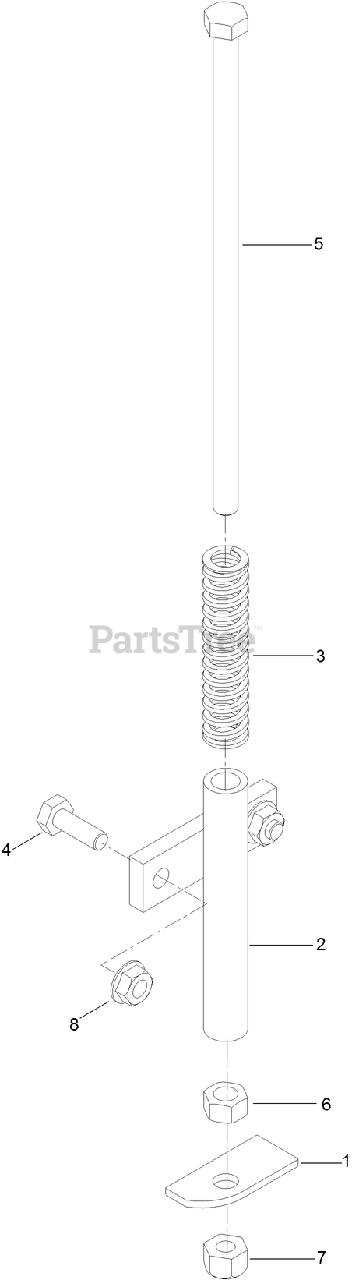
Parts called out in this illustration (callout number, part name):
1	PLATE-SWITCH
2	MOUNT-SPRING, SEAT
3	SPRING-SWITCH, SEAT
4	SCREW-HH
5	SCREW-HH
6	NUT-HEX
7	NUT-LOCK, NI
8	NUT-HF
